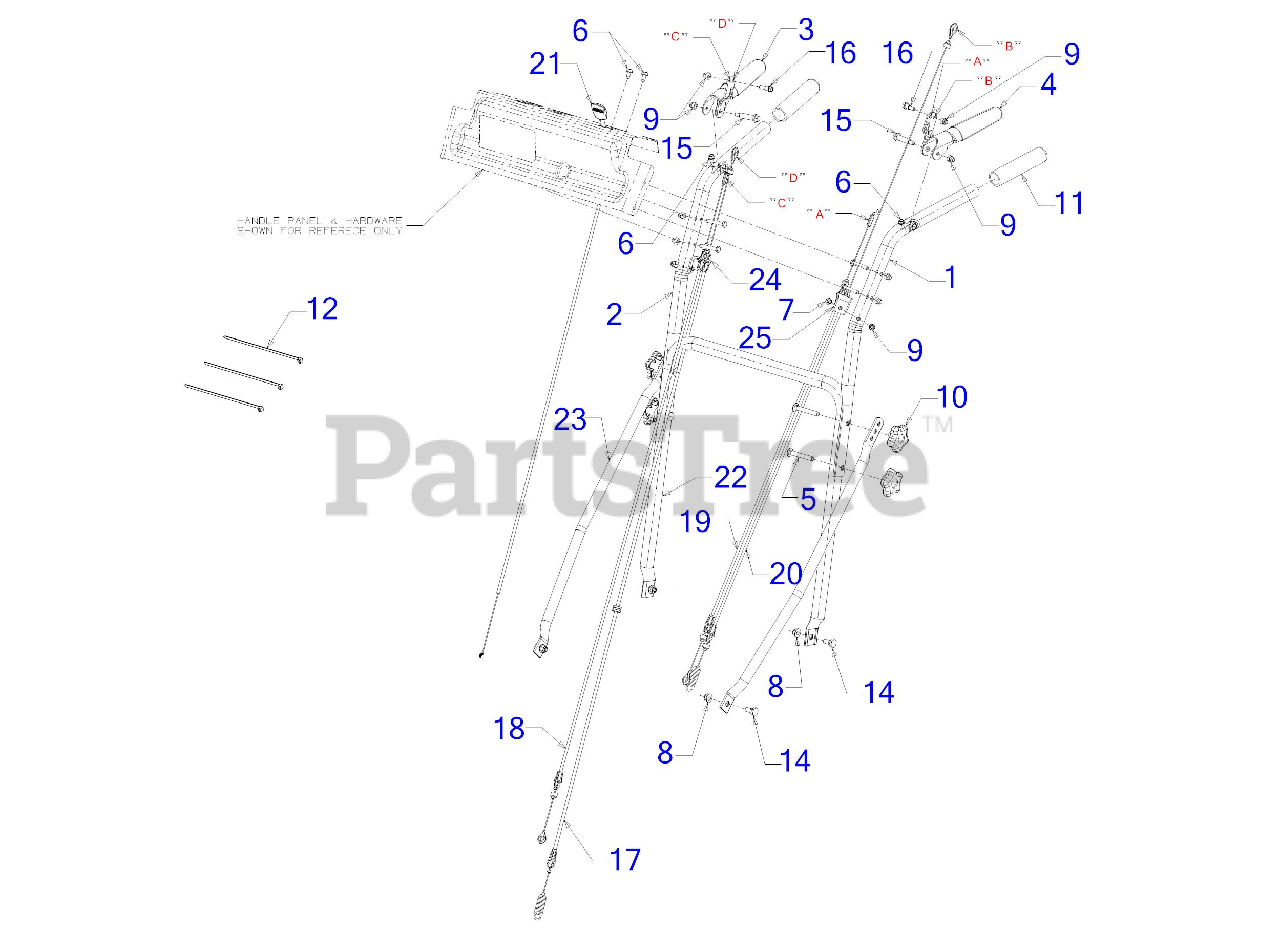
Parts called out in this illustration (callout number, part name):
1	UPPER HANDLE ASSEMBLY (LH)
2	UPPER HANDLE ASSEMBLY (RH)
3	LEVER ASSEMBLY (RH) (RED)
4	LEVER ASSEMBLY (LH) (RED)
5	SCRE W5/16-18 x 2.25 GR5
6	SCREW 1/4-20 X.500
7	SCREW 1/4-20 x 1.50 GR.5
8	FLANGE LOCK NUT 5/16-18
9	HEX ACORN NUT
10	STAR KNOB 5/16-18
12	7" CABLE TIE
14	SHOULDER SCREW .437
15	SHOULDER BOLT .375X1.285:1/4-20
16	SHOULDER SCREW .342X.335X1/4-20
17	BLADE CONTROL CABLE
18	TRANSMISSION BRAKE CABLE (RH)
19	TRANSMISSION BRAKE CABLE (LH)
20	WHEEL CLUTCH CABLE
21	THROTTLE CABLE
23	HANDLE ADJUSTMENT BRACE
24	CABLE BRACKET MOUNTING (RH)
25	CABLE BRACKET MOUNTING (LH)
